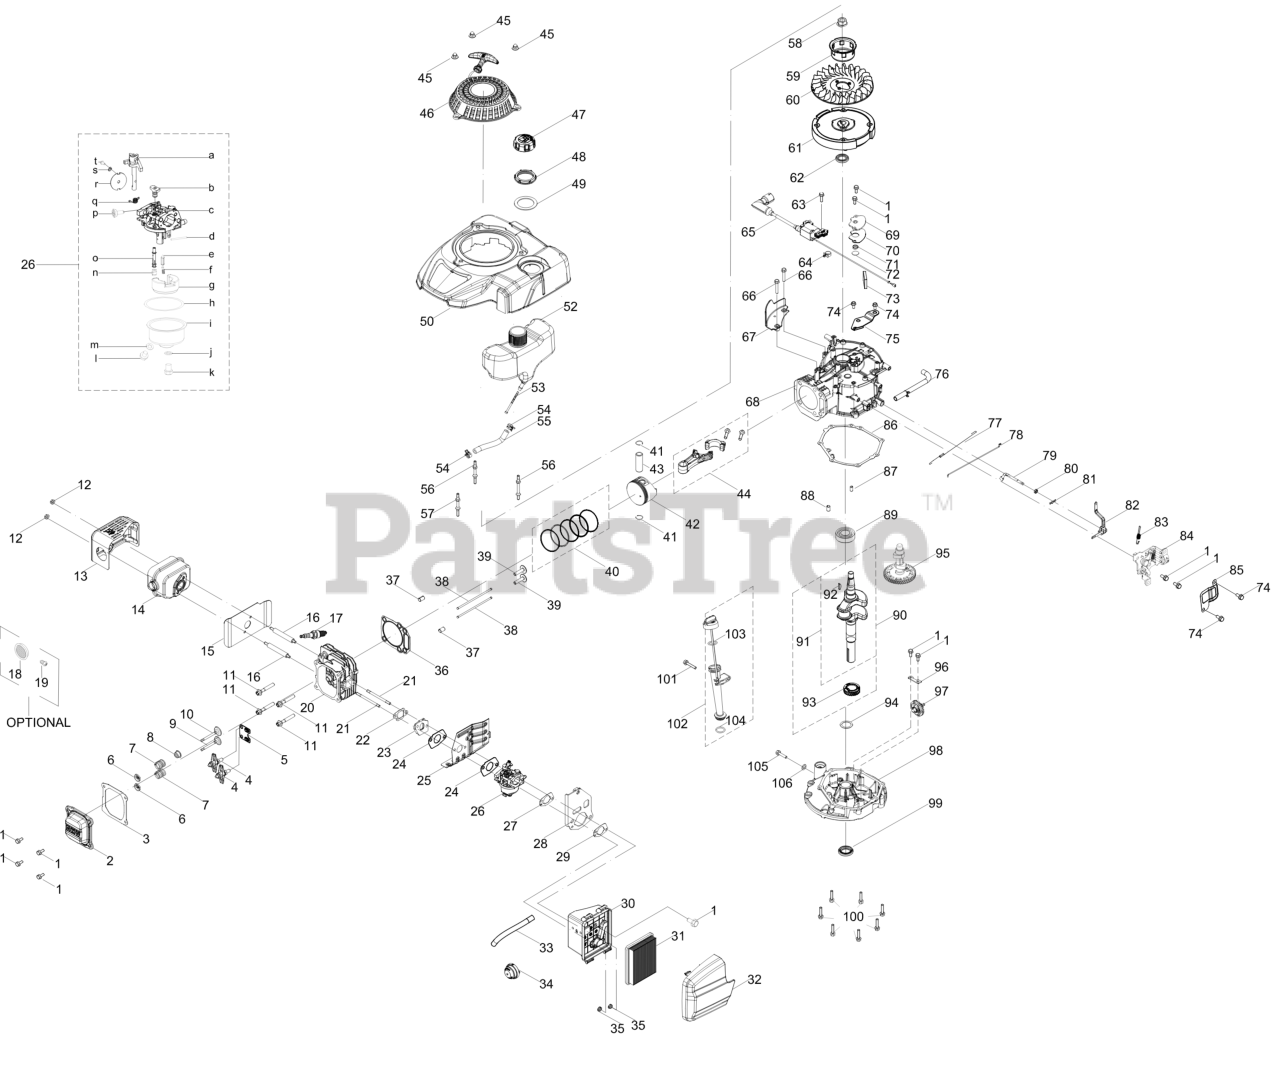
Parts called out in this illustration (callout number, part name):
1	BOLT M6-1 x 14 GR8.8
2	VALVE COVER
3	VALVE COVER GASKET
4	ROCKER ARM ASSEMBLY
5	PUSH ROD GUIDE
6	INTAKE VALVE SPRING RETAINER
7	VALVE SPRING
8	INTAKE VALVE SEAL
9	EXHAUST VALVE
10	INTAKE VALVE
11	SCREW M8 x 54 GR10
13	MUFFLER SHIELD
15	MUFFLER GASKET
16	STUD M6-1 x 95
17	SPARK PLUG
18	SPARK ARRESTOR
19	SCREW M3.5 x 9.5
20	CYLINDER HEAD
21	CARBURETOR STUD-M6 x 87
22	CARBURETOR GASKET
23	CARBURETOR INSULATOR
24	CARBURETOR GASKET
25	HEAT SHIELD
26	CARBURETOR
27	AIR FILTER BRACKET GASKET
28	AIR FILTER BRACKET
29	AIR FILTER BASE GASKET
30	AIR FILTER BASE
31	AIR FILTER
32	AIR FILTER COVER
33	PRIMER HOSE
34	VENTED PRIMER ASSEMBLY
36	CYLINDER HEAD GASKET
40	PISTON RING 4PC SET
41	PISTON PIN SNAP RING
44	CONNECTING ROD ASSEMBLY
45	ACORN NUT
46	RECOIL STARTER ASSEMBLY
47	FUEL CAP ASSEMBLY
48	FUEL TANK NUT
49	FUEL TANK UPPER GROMMET
50	ENGINE SHROUD ASSEMBLY
53	FUEL FILTER
54	HOSE CLAMP
55	FUEL HOSE
56	STARTER/SHROUD REAR STUD
57	STARTER/SHROUD FRONT STUD
58	FLYWHEEL NUT
59	COOLING FAN
60	STARTER CUP
62	CRANKSHAFT SEAL
63	BOLT M6-1 x 20 GR8.8
64	WIRE SUPPORT CLAMP
65	IGNITION COIL ASSEMBLY
66	BOLT M6-1 x 25 GR8.8
67	ENGINE BRAKE COVER PLATE
69	BREATHER COVER PLATE
70	BREATHER GASKET
71	BREATHER VALVE SPRING
72	BREATHER VALVE
73	BREATHER SCREEN
74	BOLT M6-1 x 12 GR8.8
75	AIR VANE COVER
76	BREATHER HOSE ASSEMBLY
77	THROTTLE LINKAGE SPRING
78	THROTTLE LINKAGE
79	GOVERNOR ARM SHAFT
82	GOVERNOR ARM ASSEMBLY
83	Governor Spring
84	VARIABLE SPEED CONTROL ASSEMBLY
85	VARIABLE SPEED CONTROL COVER
86	CRANKCASE COVER GASKET
87	DOWEL PIN 7 X 14
88	DOWEL PIN 9 X 14
90	CRANKSHAFT
91	CRANKSHAFT
92	WOODRUFF KEY
93	DRIVE TIMING GEAR
94	THRUST WASHER
96	GOVERNOR GEAR MOUNTING PLATE
97	GOVERNOR GEAR/SHAFT ASSEMBLY
98	CRANKCASE COVER
99	LOWER CRANKSHAFT OIL SEAL
100	BOLT-M6-1 x 28 GR8.8
101	BOLT M6-1 x 35 GR8.8
102	OIL DIPSTICK ASSEMBLY
103	O-RING
105	OIL DRAIN PLUG
106	FLAT WASHER
P	SPEED IDLE SCREW
